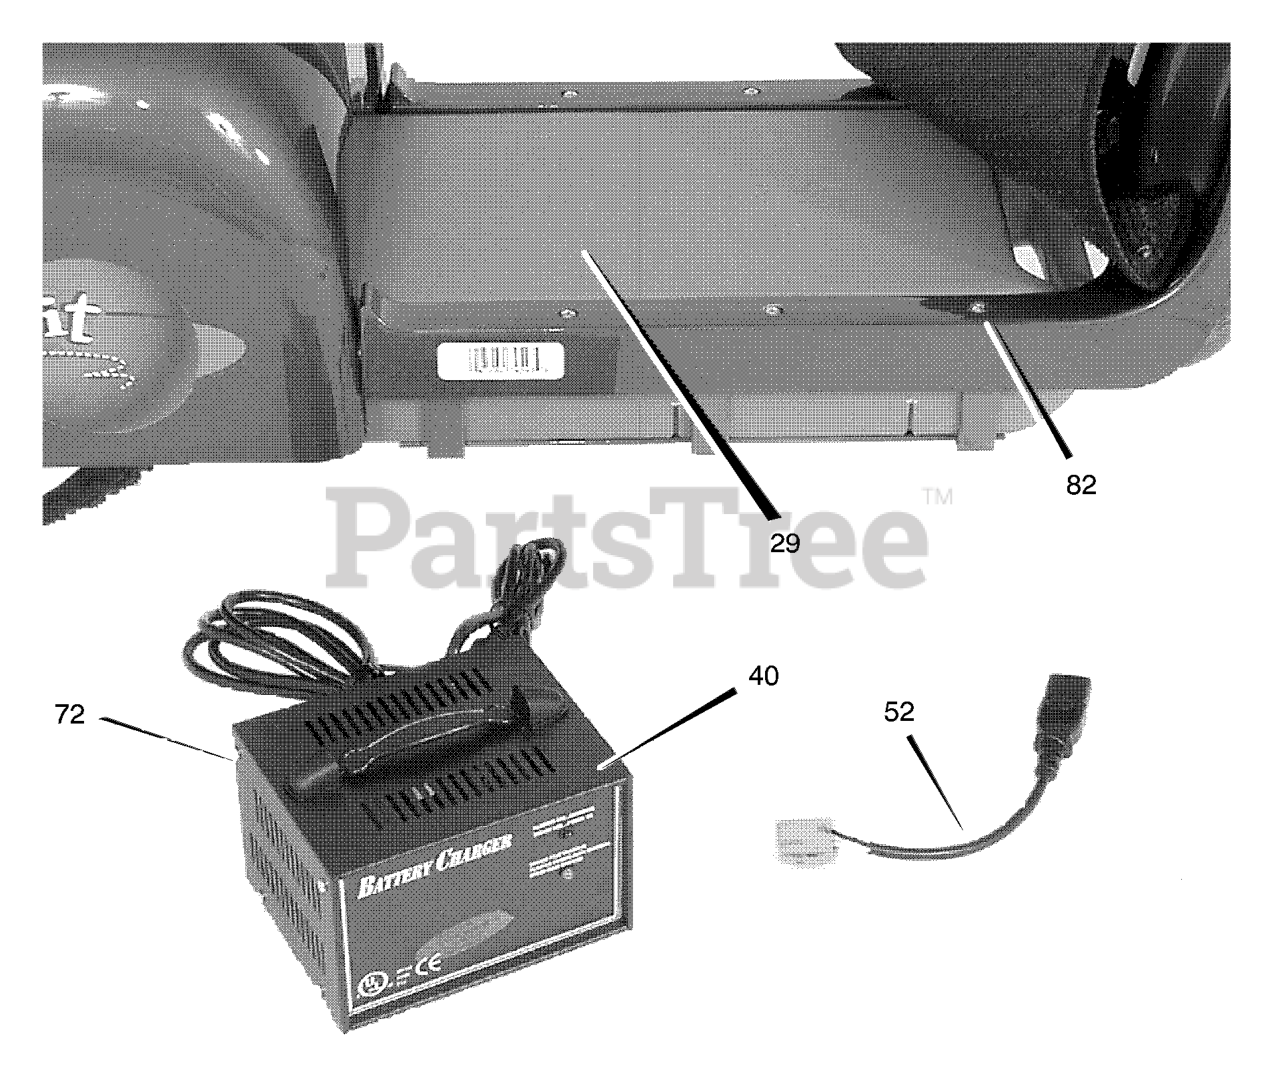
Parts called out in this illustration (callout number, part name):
29	Sealed Battery Set
40	Charger, 24 Volt
52	Adapter Plug, Remote Charging
72	Label, Charger Info
82	Screw (6 required)
